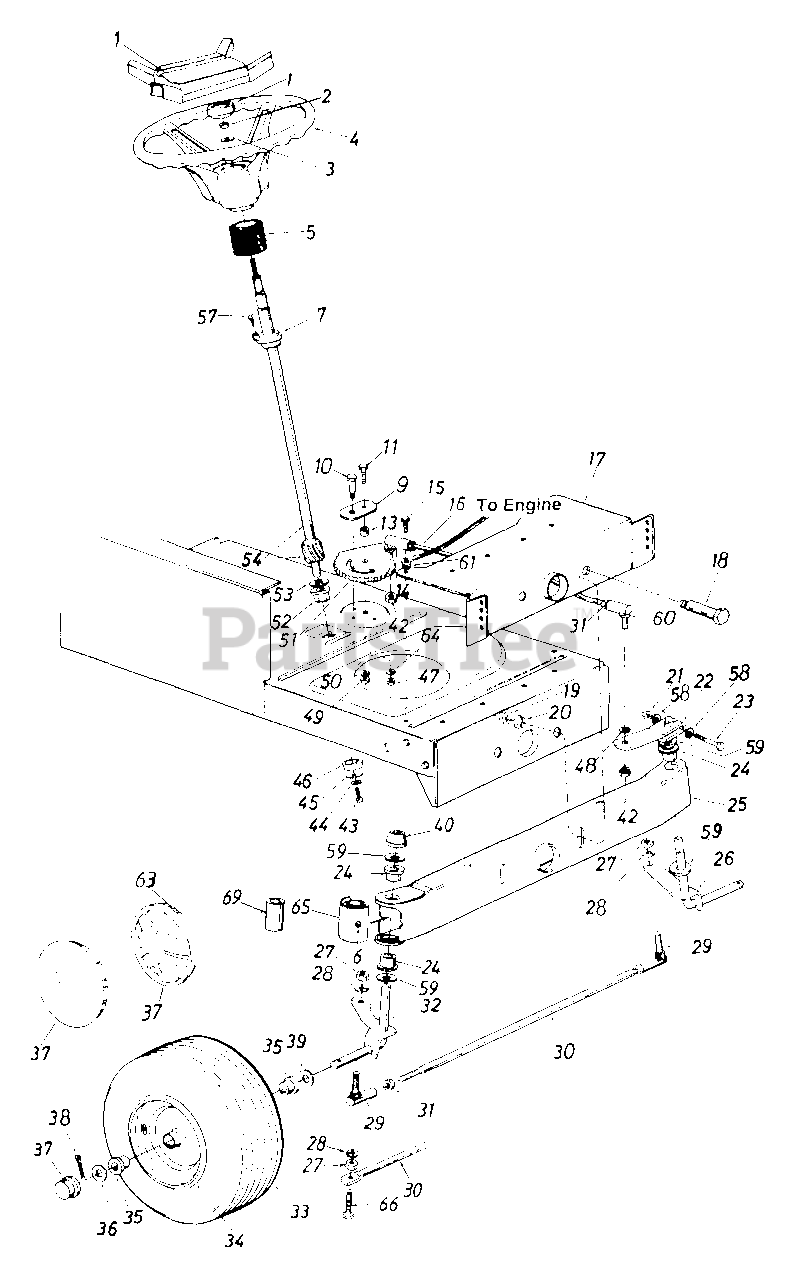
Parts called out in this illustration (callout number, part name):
1	Steering Wheel Cap
2	Hex L-Nut 5/16-24 Thd.
3	Belleville Wash. .345" I.D.
4	Steering Wheel (3 Spoke)
5	Steering Bellow - 4.5"
6	Grease Fitting
7	Flange Bearing .628" I.D. x 1.36 O.D.
9	Retainer Plate
10	Shoulder Bolt .437" Dia. x .35 Lg. 6/16-18 Thd.
11	Hex Bolt 3/8-24 x 1.0" Lg. (Grade 5)
13	Spacer .380" I.D. x .625" O.D. x.227
14	L-Wash. 3/8" I.D. (H.D.)
15	Hex Wash. Hd. Self-Tap Scr.
16	Steering Drag Link
17	Front Pivot Brkt.
18	Shoulder Bolt .498" Dia. x 2.04 Lg. 3/8-16 Thd.
19	Hex Nut 3/8-16 Thd.
20	L-Wash. 3/8" I.D.
21	Hex L-Nut 5/16-24 Thd.
22	Steering Arm Front Axle
23	Hex Bolt 5/16-24 x 2.00" Lg. (Grade 5)
24	Hex Fig. Brg. .632 I.D.
26	Front Axle Ass'y.- L.H.
27	Hex Nut 3/8-24 Thd.
28	L-Wash. 3/8" I.D.
29	Ball Joint 3/8-24 Thd.
30	Tie Rod (Adjustable)
31	Hex Jam Nut 3/8-24 Thd.
32	Front Axle Ass'y.- R.H.
33	Wheel Ass'y. Comp.
34	Front Wheel Rim Only
36	Fl-Wash. .635 I.D. x 1.59" O.D.
37	Front Wheel Hub Cap
38	Cotter Pin 1/8" Dia. x 1.25"
39	Fl-Wash. .640" I.D. x 1.24" O.D.
40	Push Cap 5/8" Dia. Rod
42	Hex Jam Nut 3/8-24 Thd.
43	Hex L-Bolt 5/16-18 x .62"
44	L-Wash. 5/16" I.D."
45	Fl-Wash. .33" I.D. x 1.25" O.D.
46	Spacer (Plastic)
47	Hex Cent. L-Nut 3/8-24 Thd.
48	L-Wash. 3/8" I.D.
49	Hex Cent. L-Nut 5/16-18 Thd.
50	L-Wash. 5/16" I.D.
51	Steering Gear Segment
52	Hex Fig. Brg. .634 I.D.
53	Fl-Wash. (Hardened)
54	Steering Shaft
57	Oval Hd. Cr.- Sunk Scr. #10 x 5/8" Lg.
58	Wave-Wash. .32" I.D. x.62" O.D.
59	Fl-Wash. (Hardened)
60	Drag Link Ball Joint 3/8-24 Thd.
61	Ext. L-Wash. 5/16" I.D.
63	Spring Clip
64	Bell-Wash. .39" I.D. x 1.38" O.D.
65	Pivot Bar End Cap
66	Hex Bolt 3/8-24 x 1.5" Lg. (Gr. 5)
69	Plastic Tube 1.54" Lg.
